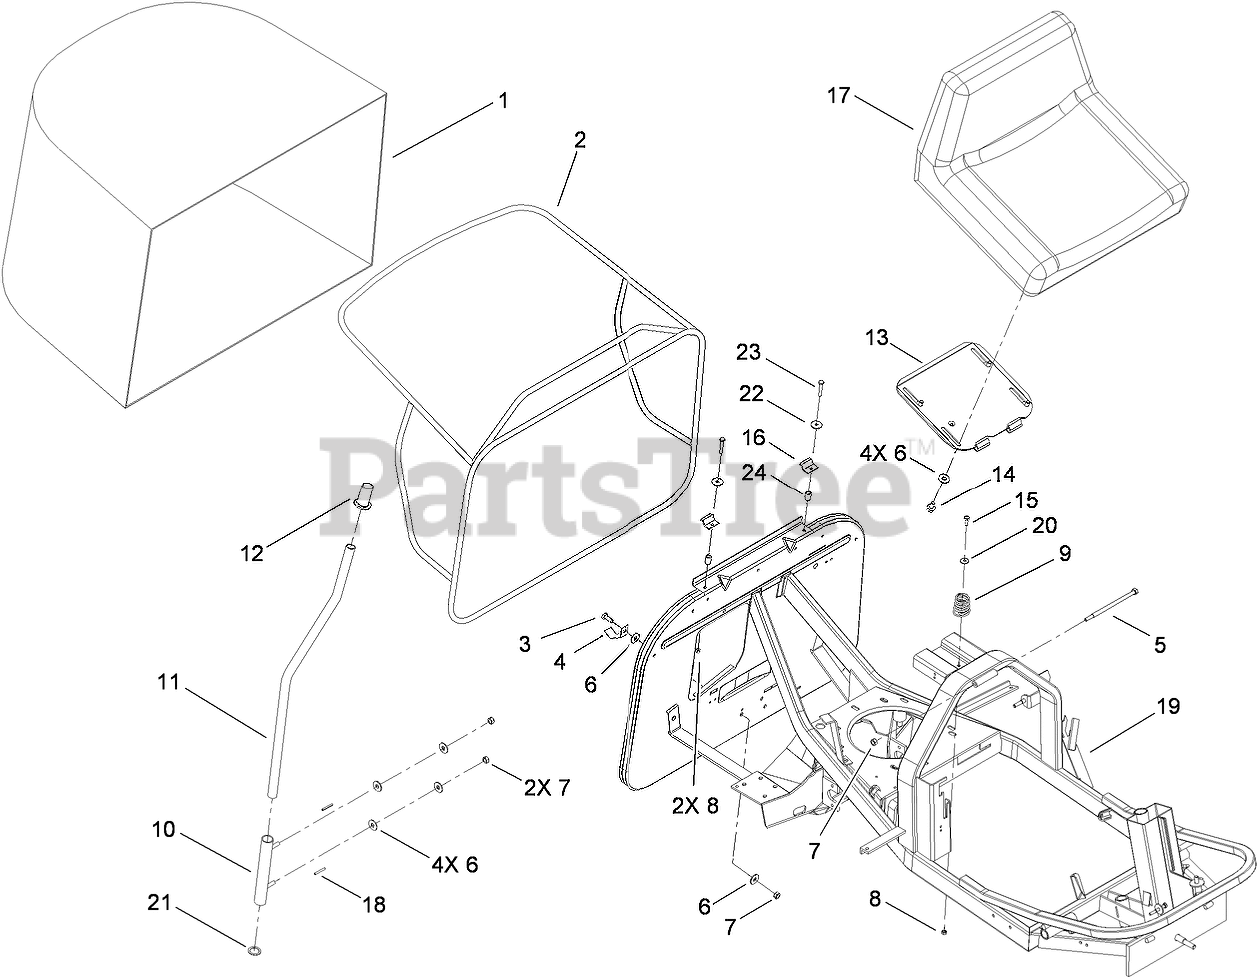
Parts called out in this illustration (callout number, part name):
1	BAG-GRASS
2	FRAME-COLLECTOR
3	SCREW-HH
4	Hook-Bag
5	Screw-HH
6	Washer-Flat
7	NUT-LOCK
8	NUT-LOCK
9	Spring-Compression
10	Support
11	Lever
13	Plate-Seat
14	SCREW-HHF
15	SCREW-HH
18	Pin-Spring
19	FRAME-COMPLETE
20	Washer-Flat
21	Spacer
22	Washer-Flat
23	SCREW-HH
24	SPACER-COLLECTOR
